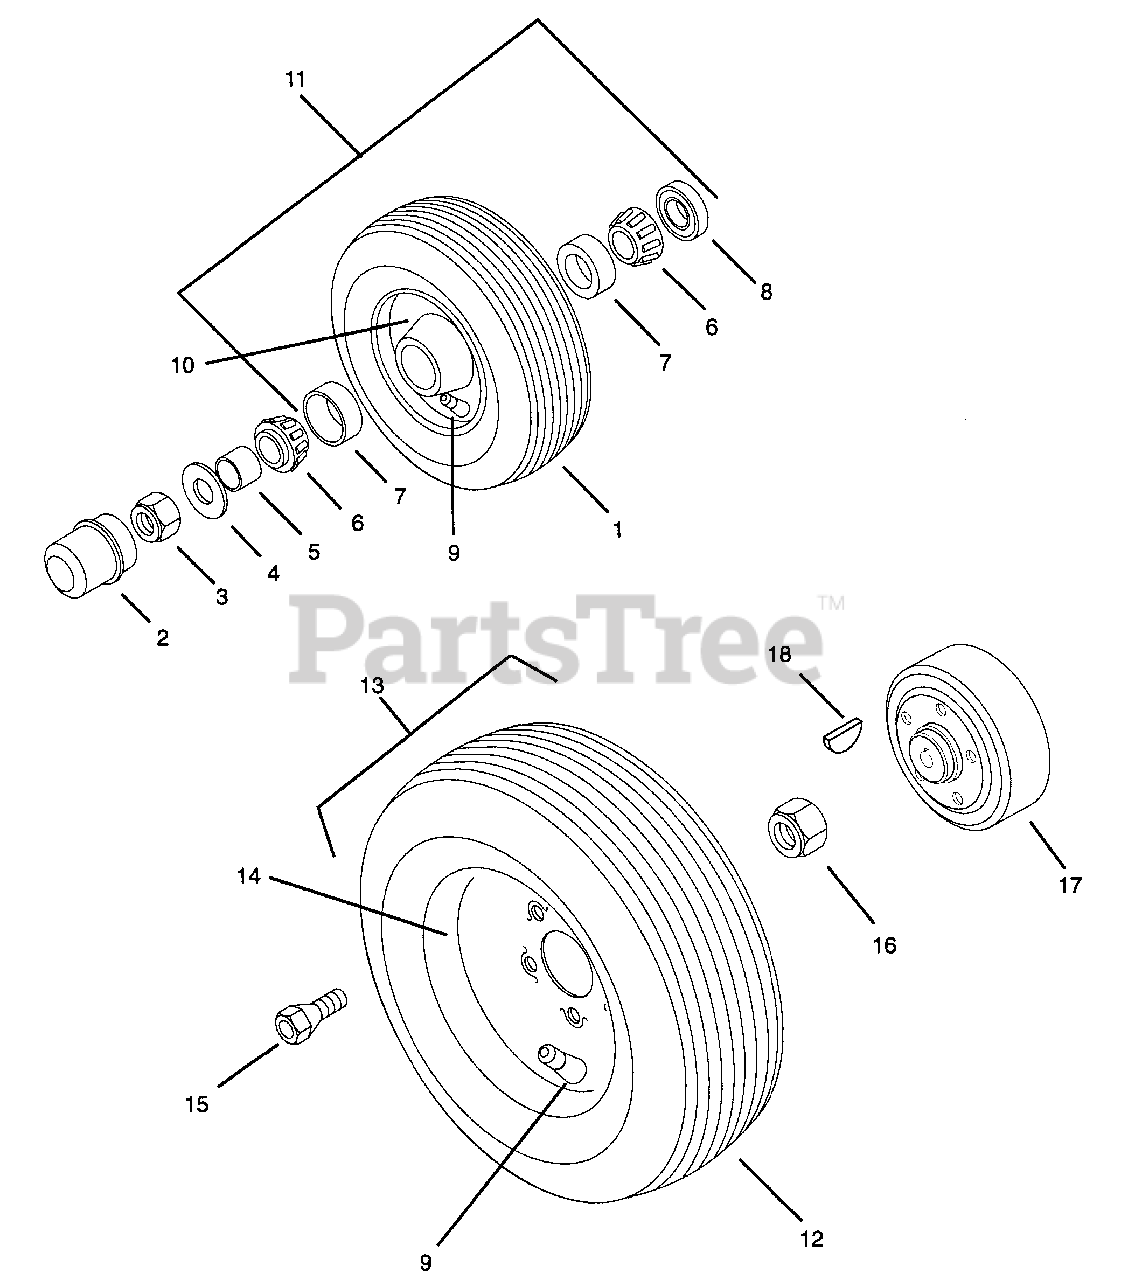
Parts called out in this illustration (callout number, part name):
1	Tire,Front 16 X 7.50-8
2	Dust Cap
3	Nut-Lock-Center .625-11
4	Washer-Flat-Steel .656 x 1.312 x .095
5	Spacer .752 x 1.000 x .500
6	Bearing-Cone .750 x .61
7	Bearing-Cup 1.78 x .475
8	Seal 1.206 x 1.785 x .468
9	ValveStem Assembly
10	Tire/Wheel Assembly 16 x 7.50-8
11	Tire,Front Assembly
12	Tire/Wheel Assembly 23 x 10.50-12
13	Tire,Rear 23 x 10.50-12
14	Weldment,Rim
15	Bolt .44-20 x 1.0
16	Nut-Locking 1.00-14
17	Hub,Wheel
18	Key-Square .312 x 2.25
